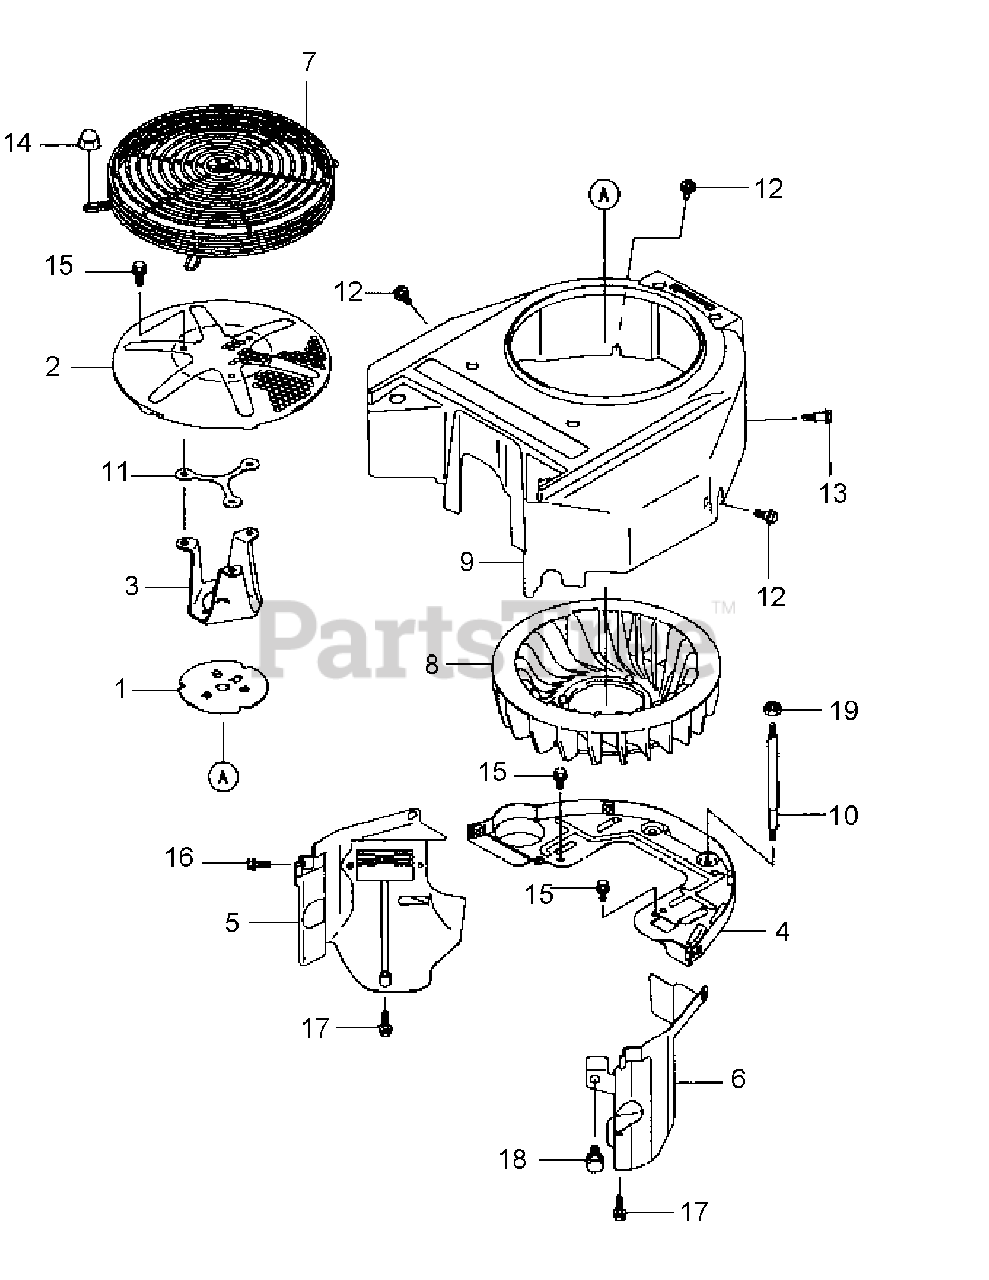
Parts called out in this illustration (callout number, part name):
4	ENGINE SHROUD
5	ENGINE SHROUD
6	ENGINE SHROUD
8	FAN
9	FAN HOUSING
11	SPACER
13	BOLT
15	FLANGED BOLT
16	FLANGED BOLT
17	FLANGED BOLT
18	FLANGED BOLT
